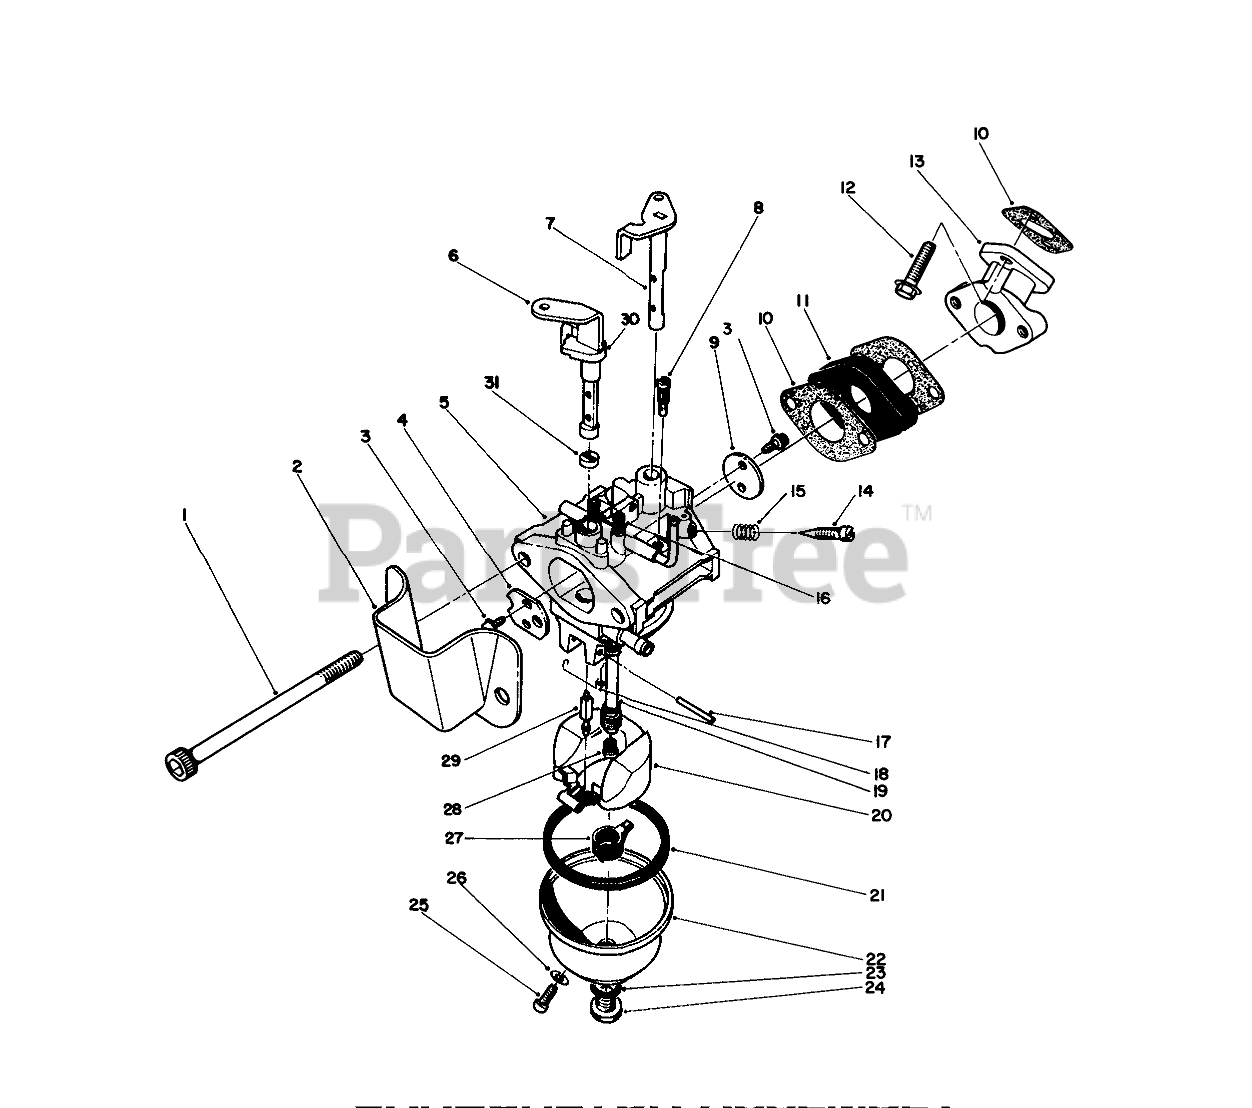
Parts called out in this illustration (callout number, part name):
2	SPIT CUP
3	Screw
4	VALVE
5	Body-Carburetor
6	Shaft-Choke (Incl. Ref. #30 & 31)
7	SHAFT
9	VALVE
10	Gasket-Carburetor
11	CARB INSULATOR
13	MANIFOLD
14	ADJUSTER
15	SPRING-PILOT SCREW
16	SPRING
17	PIN-HINGE
18	TORSION SPRING
19	MAIN NOZZLE
20	FLOAT
21	FLOAT BOWL GASKET
23	GASKET
24	SCREW
25	SCREW
26	GASKET
27	SPACER
28	MAIN JET
29	NEEDLE
30	UPPER CHOKE RING
31	LOWER CHOKE RING
